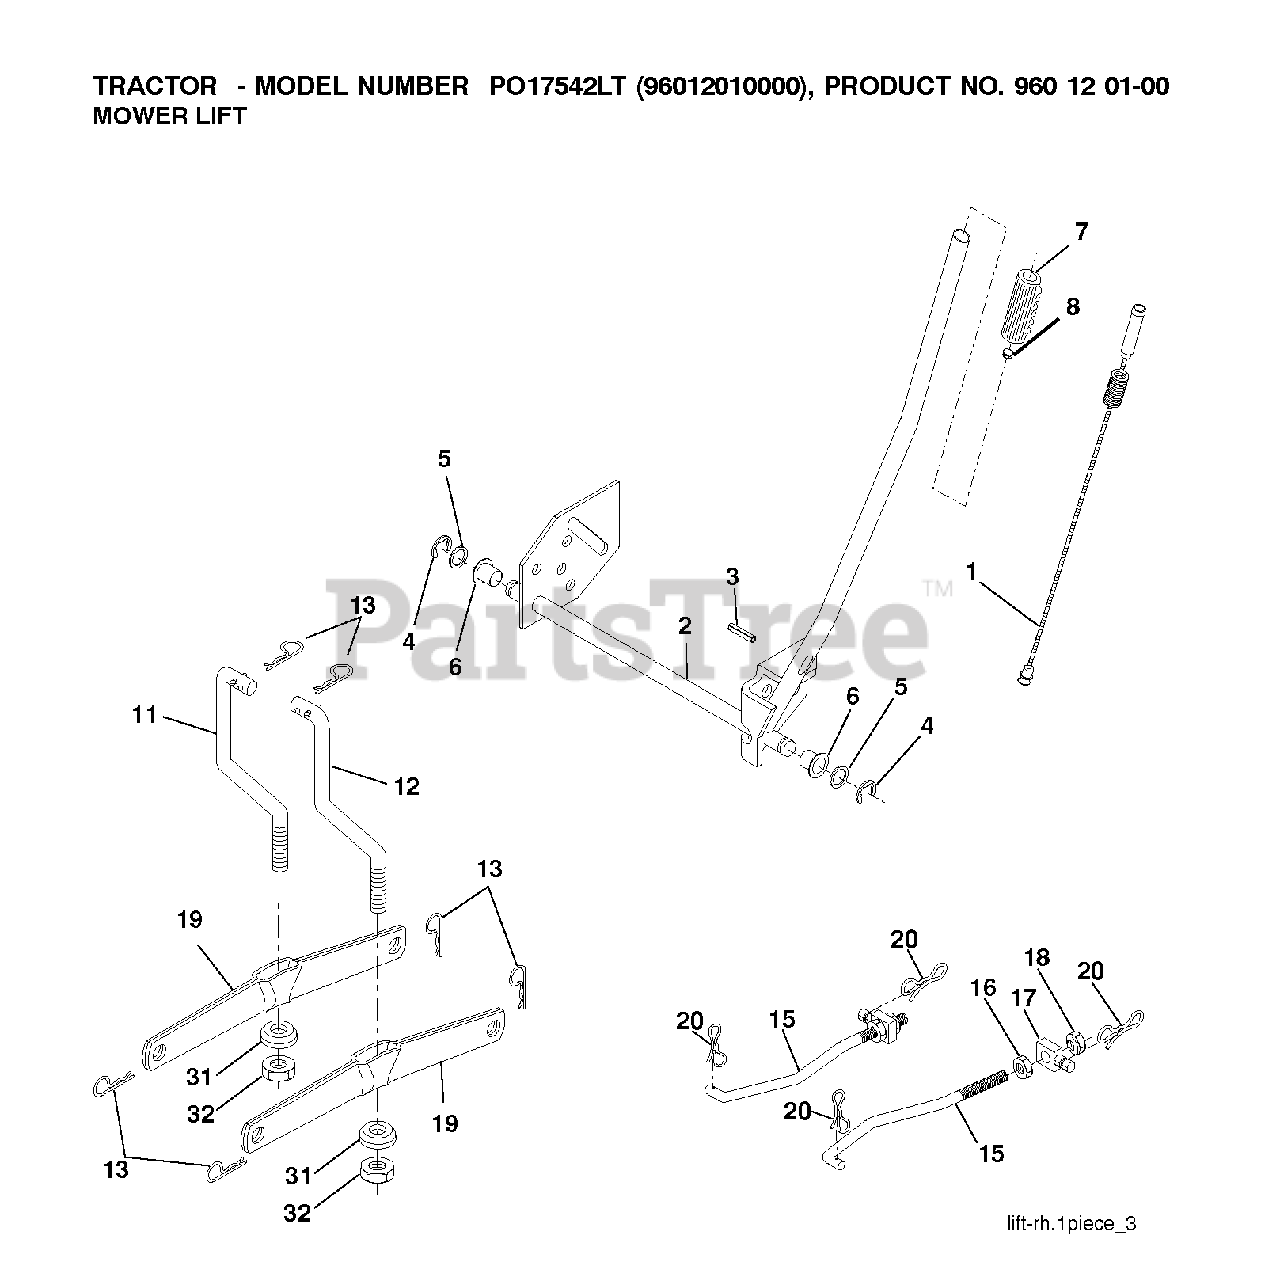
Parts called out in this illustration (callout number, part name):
1	PLUNGER.ASM.LIFT.LVR.BLK.17.32
2	SHAFT ASM R HANDLE
3	PIN GROOVE.
4	RETAINING RING LT
6	BEARING.NYLON
7	GRIP HANDLE
8	PLUNGER BUT KIT
11	LINK LIFT LH
12	Lift Link Assembly, RH
13	RETAINER-SPRNG RB
15	LINK.SUSPENSION.FRONT
16	NUT.HEX.JAM.1/2-13
17	TRUNNION
18	NUT.LK.W/WSH.1/2.
19	ARM.REAR.SUSPENSION
20	PIN.COTTER.7/16.BOW TI.
31	BEARING.PIVOT.LIFT
32	NUT CROWNLOCK 3/8-24
